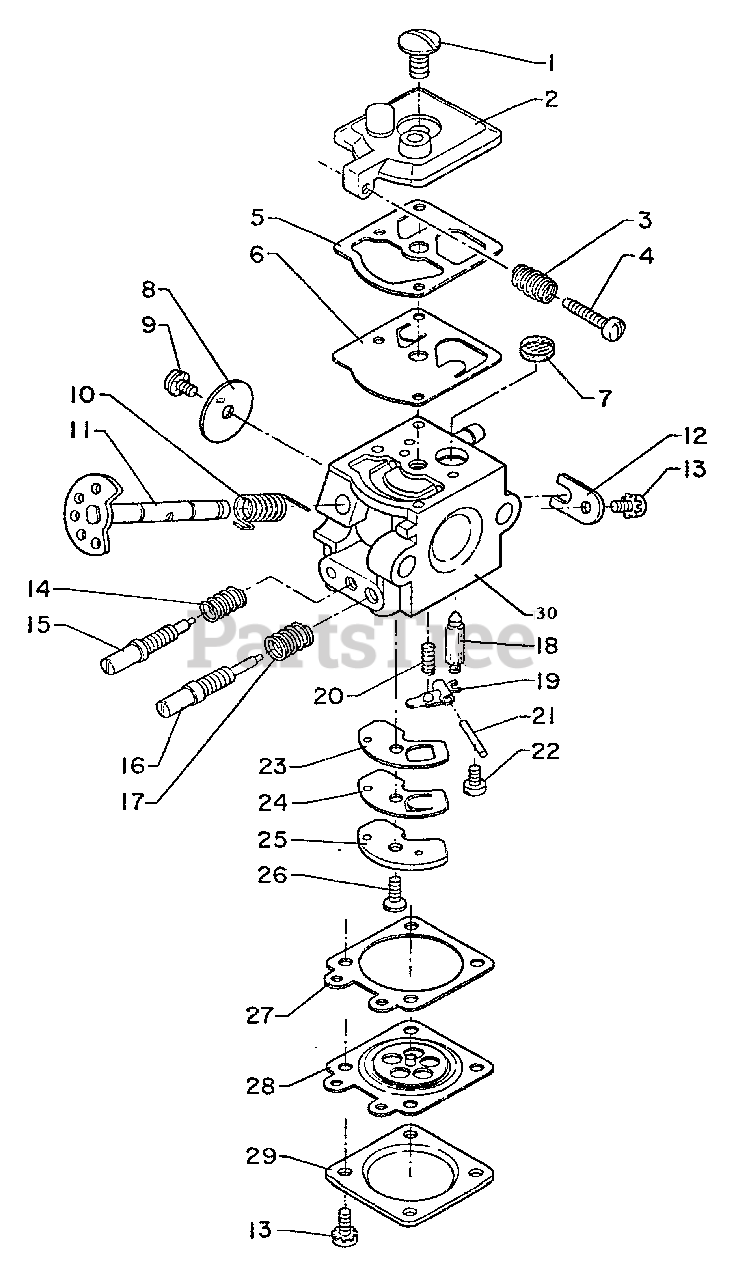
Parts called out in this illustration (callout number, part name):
2	COVER, PUMP
3	SPRING, IDLE ADJUST
4	SCREW, IDLE ADJUST
5	GASKET, FUEL PUMP
6	DIAPHRAGM, FUEL PUMP
7	STRAINER
8	VALVE, THROTTLE
10	SPRING, THROTTLE RETURN
11	SHAFT, THROTTLE
12	CLIP, THROTTLE SHAFT
14	SPRING, NEEDLE
15	NEEDLE, IDLE
16	NEEDLE, HIGH SPEED
17	SPRING, NEEDLE
18	VALVE, INLET NEEDLE
19	LEVER, METERING
21	PIN, METERING LEVER
22	SCREW, METERING LEVER PIN
23	GASKET, CIRCUIT PLATE
24	VALVE, CHECK
25	PLATE, CIRCUIT
26	SCREW, CIRCUIT PLATE
27	GASKET, METERING DIAPHRAGM
28	DIAPHRAGM, METERING
29	COVER, METERING DIAPHRAGM
30	BODY, CARBURETOR
